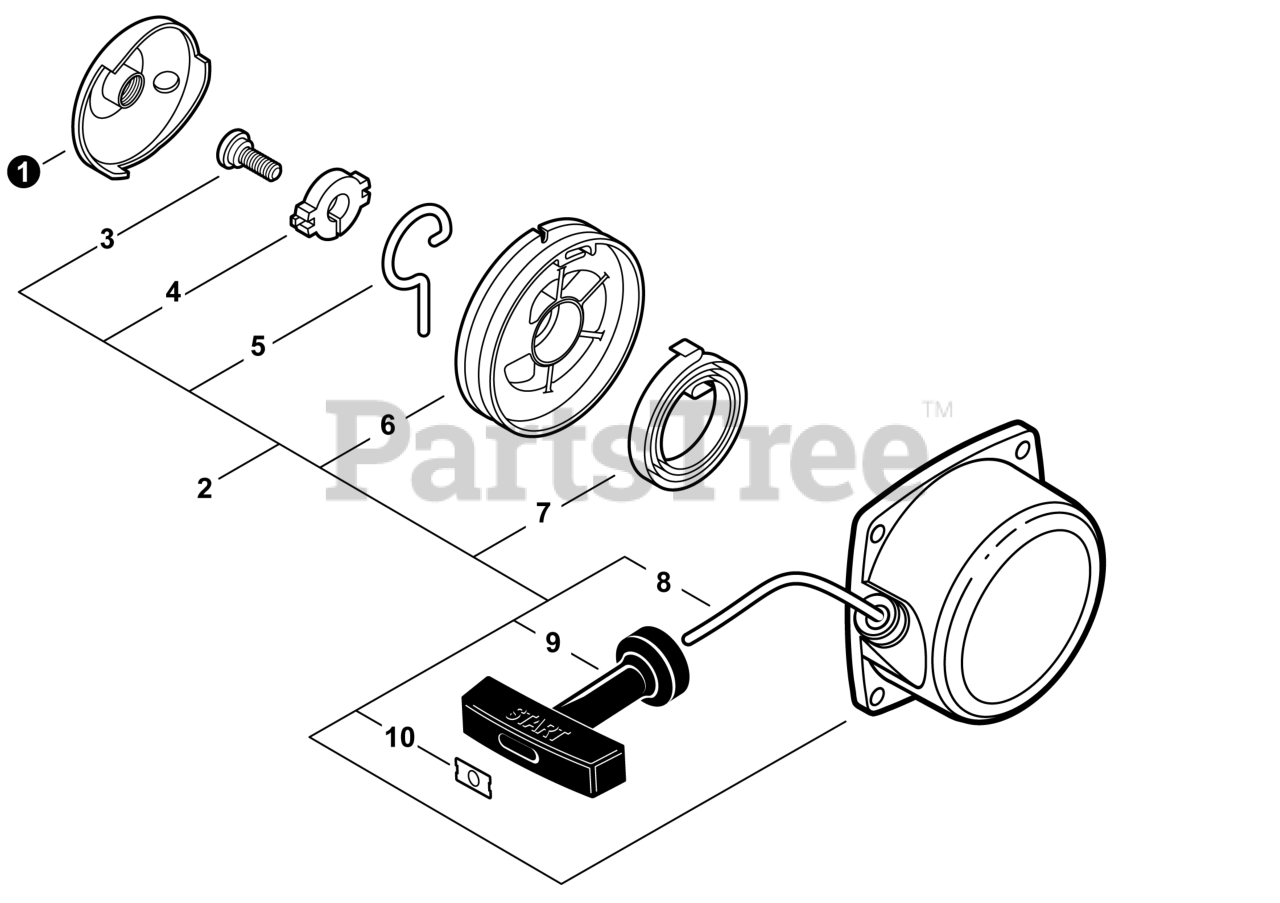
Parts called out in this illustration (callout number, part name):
1	PULLEY, STARTER
2	STARTER ASSY, RECOIL
3	SCREW 5
4	WASHER 5
5	ARM, SWING
6	REEL, ROPE
7	SPRING, RECOIL
8	ROPE, STARTER
9	GRIP, STARTER
10	RETAINER, ROPE
